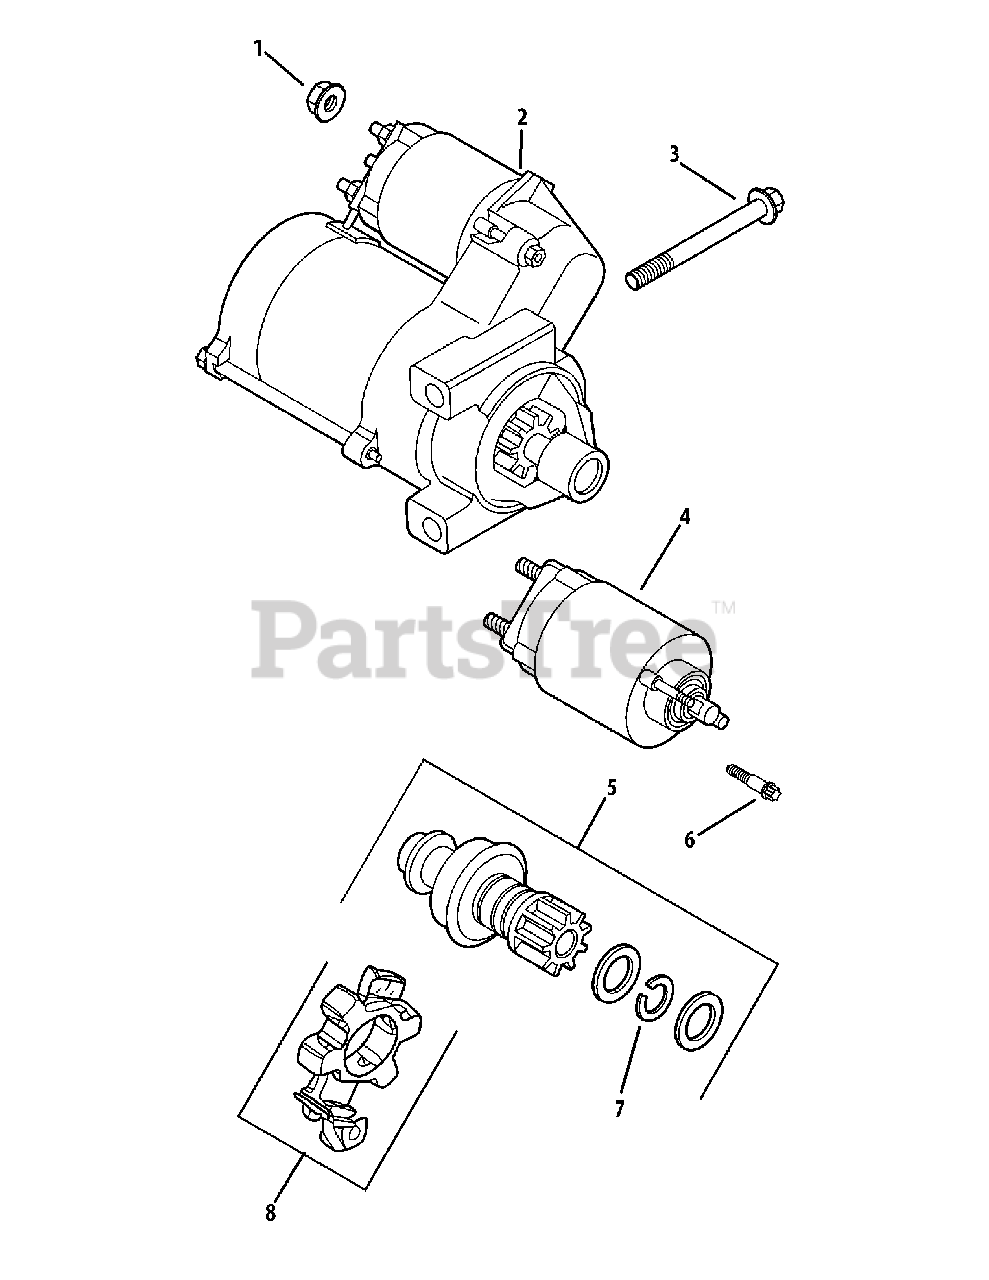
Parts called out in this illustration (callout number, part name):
1	Flange Nut, M8 x 1.25
2	Electric Starter (Solenoid Shift)
3	Flange Screw, M8 x 1.25 x 80
5	Starter Pinion Kit
6	External Torx Head Screw
7	Retaining Ring
8	Brush Holder Kit
